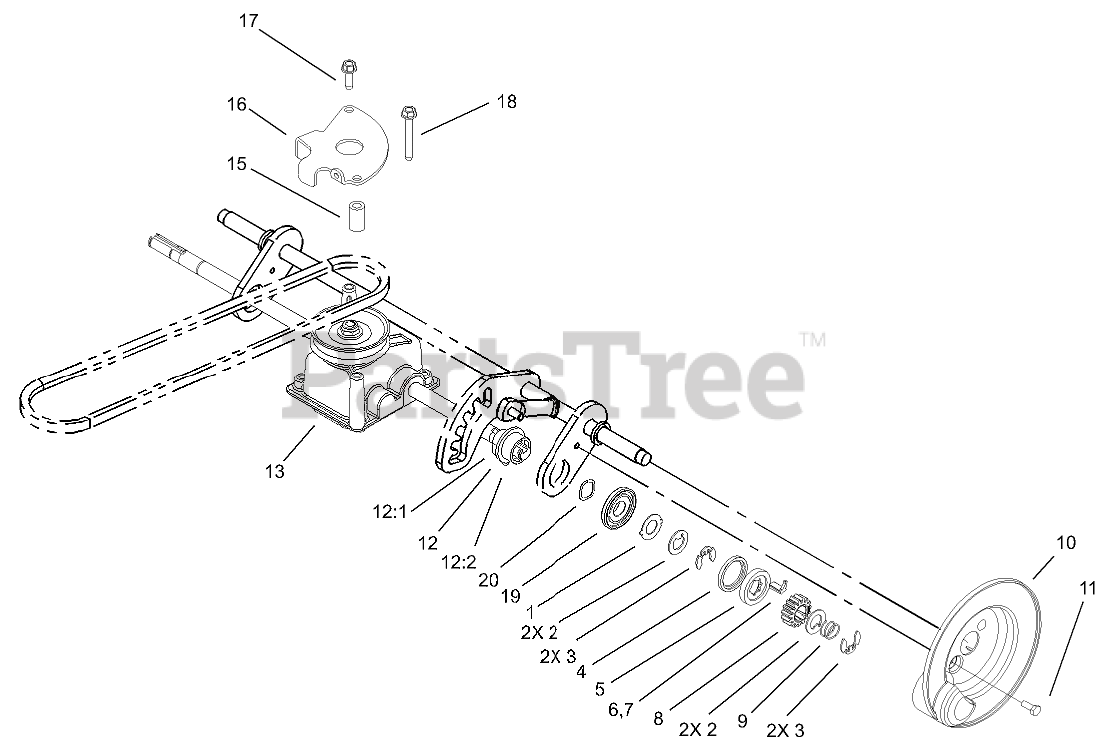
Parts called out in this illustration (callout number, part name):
1	WASHER-ARM, PIVOT
2	WASHER-THRUST, KEYED
3	RING-CLIP, LOCKING
4	RING-FRICTION
5	WASHER-CLUTCH
6	KEY-ROCKING, RH
7	KEY-ROCKING, LH
8	GEAR-PINION
9	SPRING-COMPRESSION
10	COVER-GEAR
11	SCREW-TAPTITE
12	BUSHING ASM
12:1	BUSHING
12:2	FITTING-GREASE
13	GEAR CASE ASM
15	BUSHING-PLATE, ACTUATOR
16	GUIDE-TRANSMISSION
17	SCREW-HWHTF
18	SCREW-HWHTF
19	RETAINER-RING
20	WASHER-WAVE
